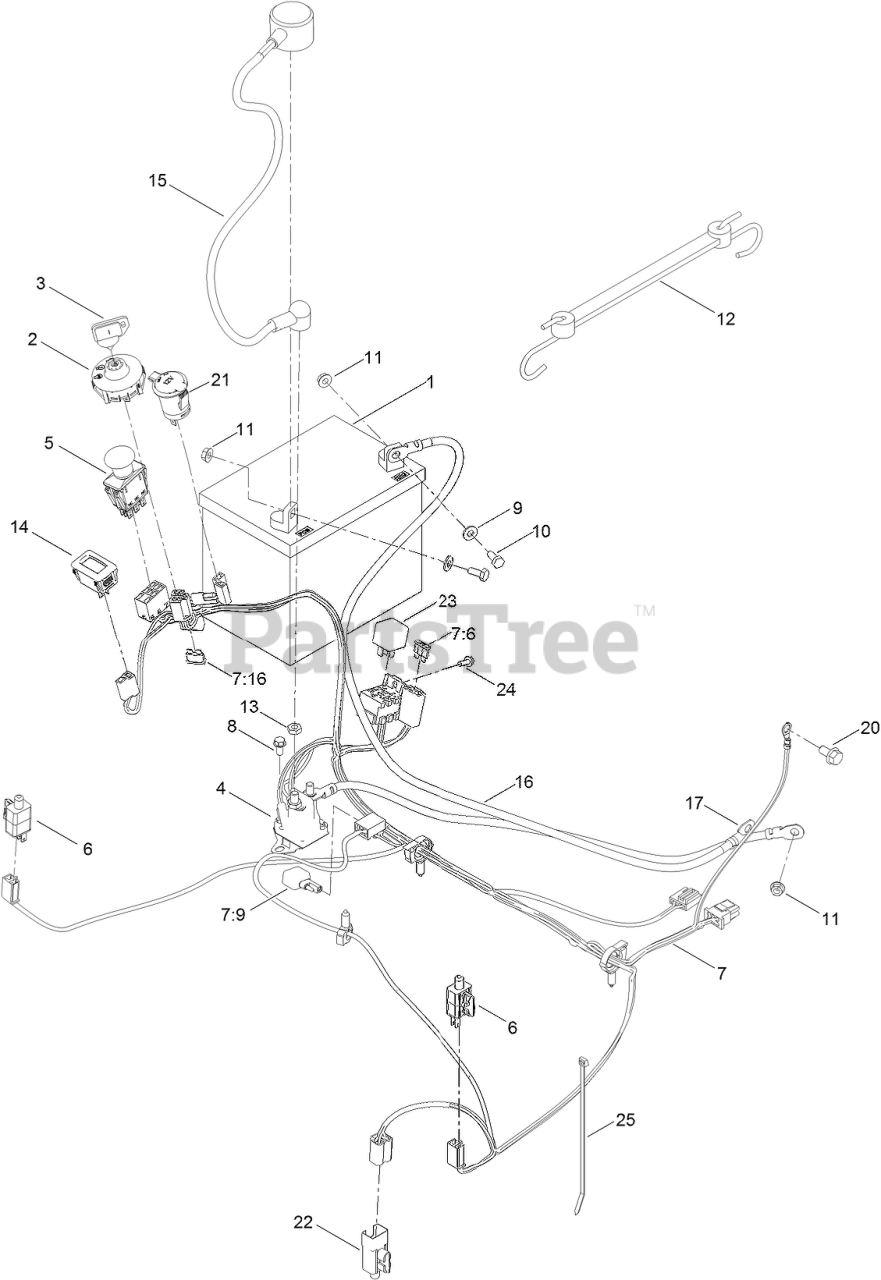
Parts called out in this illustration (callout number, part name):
1	BATTERY
2	SWITCH-IGNITION
4	SOLENOID
5	SWITCH-PTO
6	SWITCH
7	HARNESS-WIRE
7:6	FUSE-BLADE, 25 AMP
7:16	FUSE-BLADE, 15 AMP
8	SCREW-HWH
9	WASHER-FLAT
10	SCREW-HH
11	NUT-HF
12	HOLDDOWN-BATTERY
13	NUT-JAM
14	HOURMETER
15	CABLE-BATTERY, POSITIVE
16	CABLE-BATTERY, POSITIVE
17	CABLE-BATTERY, NEGATIVE
20	SCREW-HHF
21	PORT-POWER, 12V
22	SWITCH-REVERSE
23	RELAY
24	SCREW-TAPTITE
25	TIE-CABLE
